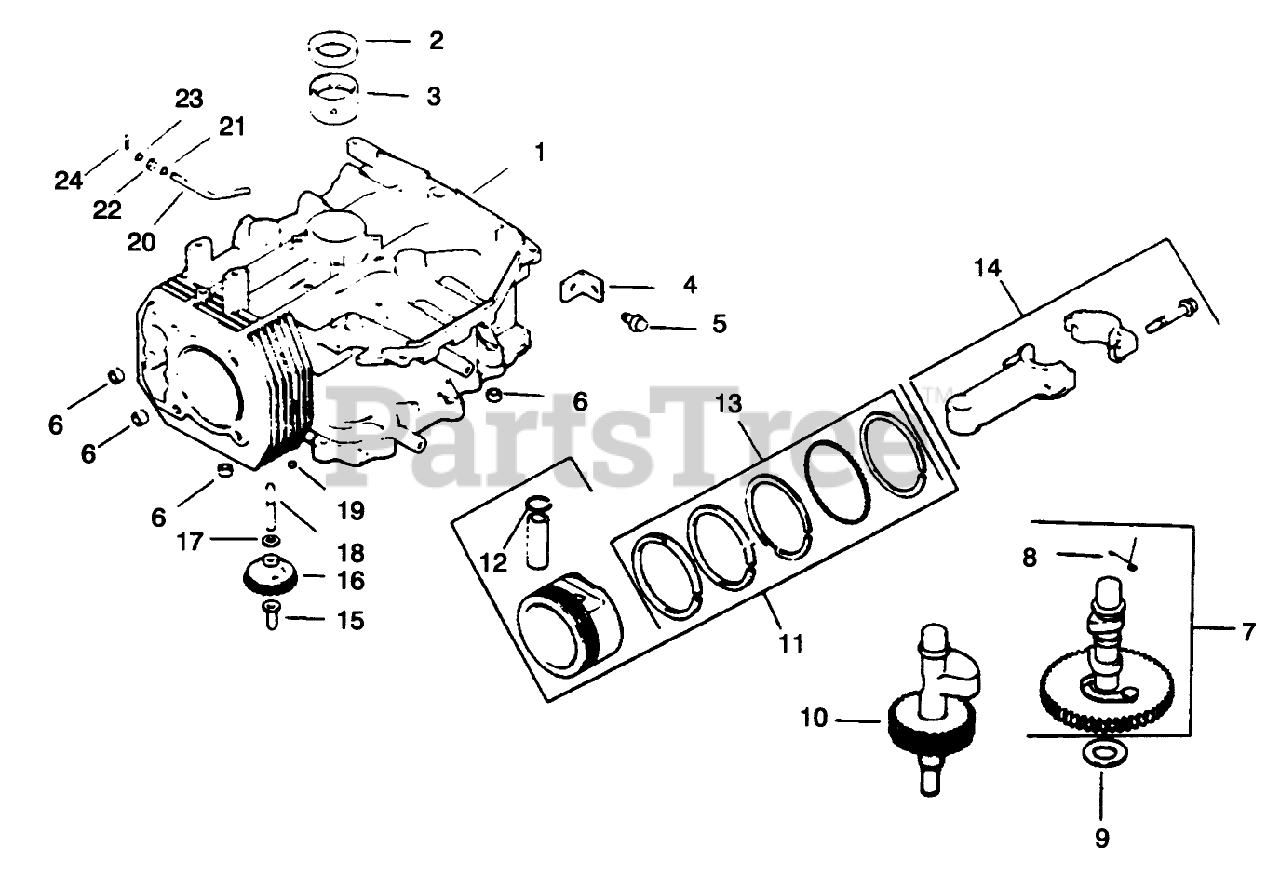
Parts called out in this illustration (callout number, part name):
1	Short Block
2	Seal-Crankshaft (Only On: 72042, 72043, 72062, 72063)
3	Bearing-Crankshaft
4	Strap-Lifting (Only On: 72042,72043,72062,72063)
5	Screw M8x1.25x22 (Only On: 72042, 72043, 72062, 72063)
6	Pin-Dowel
7	Camshaft Assembly
8	Spring-Actuating (Only On: 72042,72043,72062,72063)
9	Shim-Camshaft
10	Shaft-Balance
11	Piston W/Ring Set (Std.)
12	Retainer-Piston Pin (Only On: 72042, 72043,72062,72063)
13	Ring Set STD (Only On: 72042,72043,72062,72063)
14	Connecting Rod STD (Only On: 72042, 72063, 72062, 72043)
15	Pin-Governor
16	Gear-Governor ASM (Only On: 72042, 72063, 72062, 72043)
18	Shaft-Govenor Gear
20	Shaft-Governor Cross (Only On: 72042, 72063, 72062, 72043)
21	Washer
22	Seal
23	Washer-Governor Shaft (Only On: 72042, 72063, 72062, 72043)
24	Pin-Hitch
